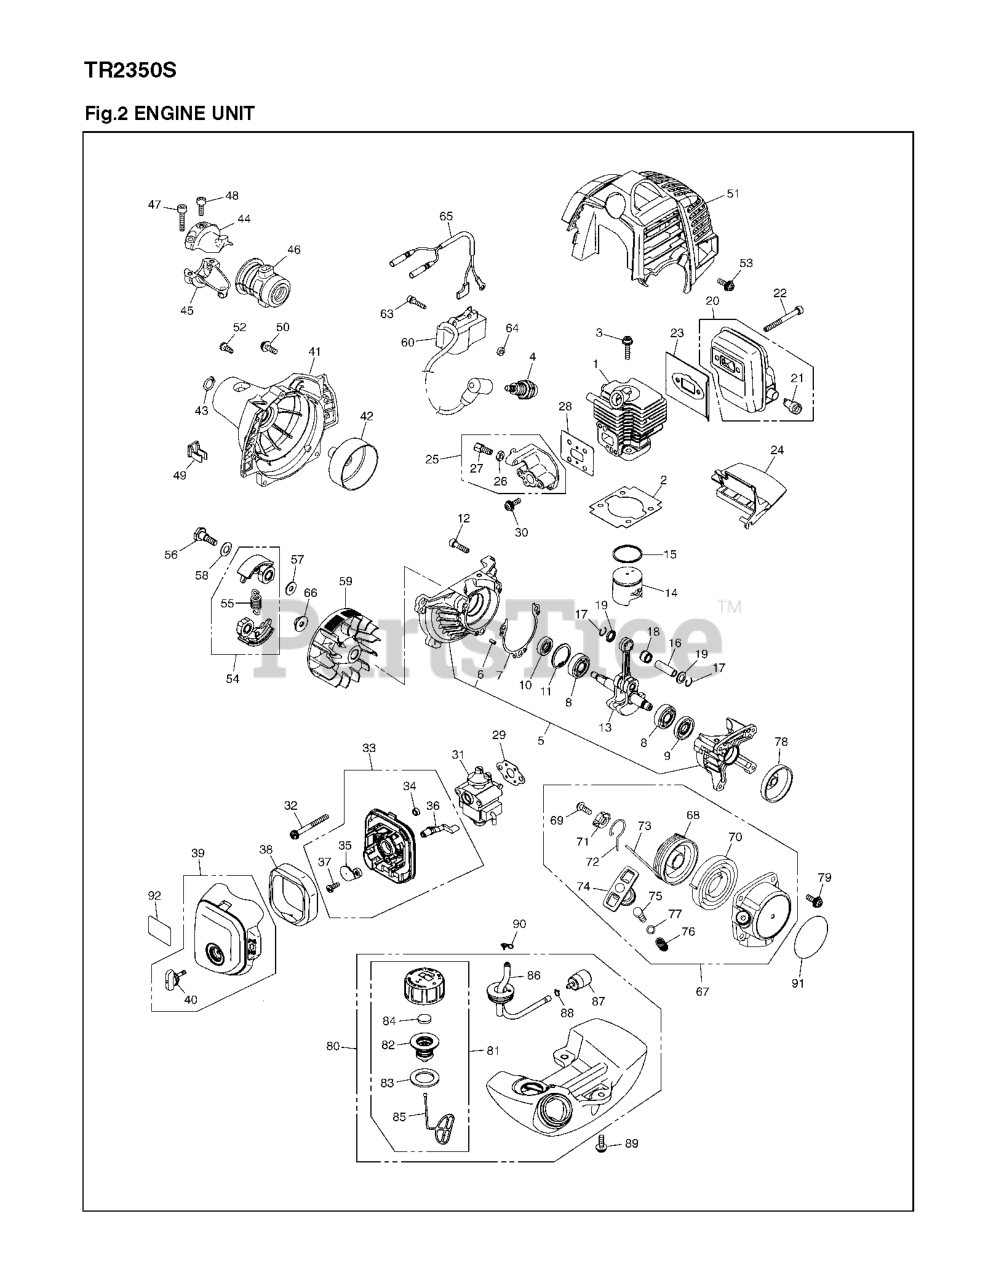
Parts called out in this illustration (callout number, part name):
1	CYLINDER
4	SPARK PLUG BPMR7Y
5	CRANKCASE-C
6	PIN
7	GASKET.CASE
11	RING,SNAP M26x1.2 RP-318013340
12	BOLT
13	CRANKSHAFT-C
15	PISTON RING
16	PIN.PISTON
20	MUFFLER-A
21	ARRESTER
22	BOLT, M5 x 50 (RPLS 125230550)
25	INSULATOR-C
26	NUT
27	SCREW (RPLS 191881170)
31	CARBURETOR-A
35	PLATE.CHOKE
36	LEVER CHOKE
37	SCREW
41	HOUSING (RPLS 848E3L5310)
42	DRUM (RPLS 481031120-22)
44	BRACKET (A) (RPLS T170031211)
45	BRACKET (B)
47	BOLT
48	BOLT
51	COVER, ENGINE
54	SHOE COMP
60	COIL (RPLS 848E487120)
64	SPACER
65	CROD COMP
67	RECOIL-A
71	COLLAR
75	COLLAR (RPLS T160075320)
80	ASSY TANK EVAP
82	HOLDER-A
86	PIPE COMP
88	CLIP
90	CLIP
